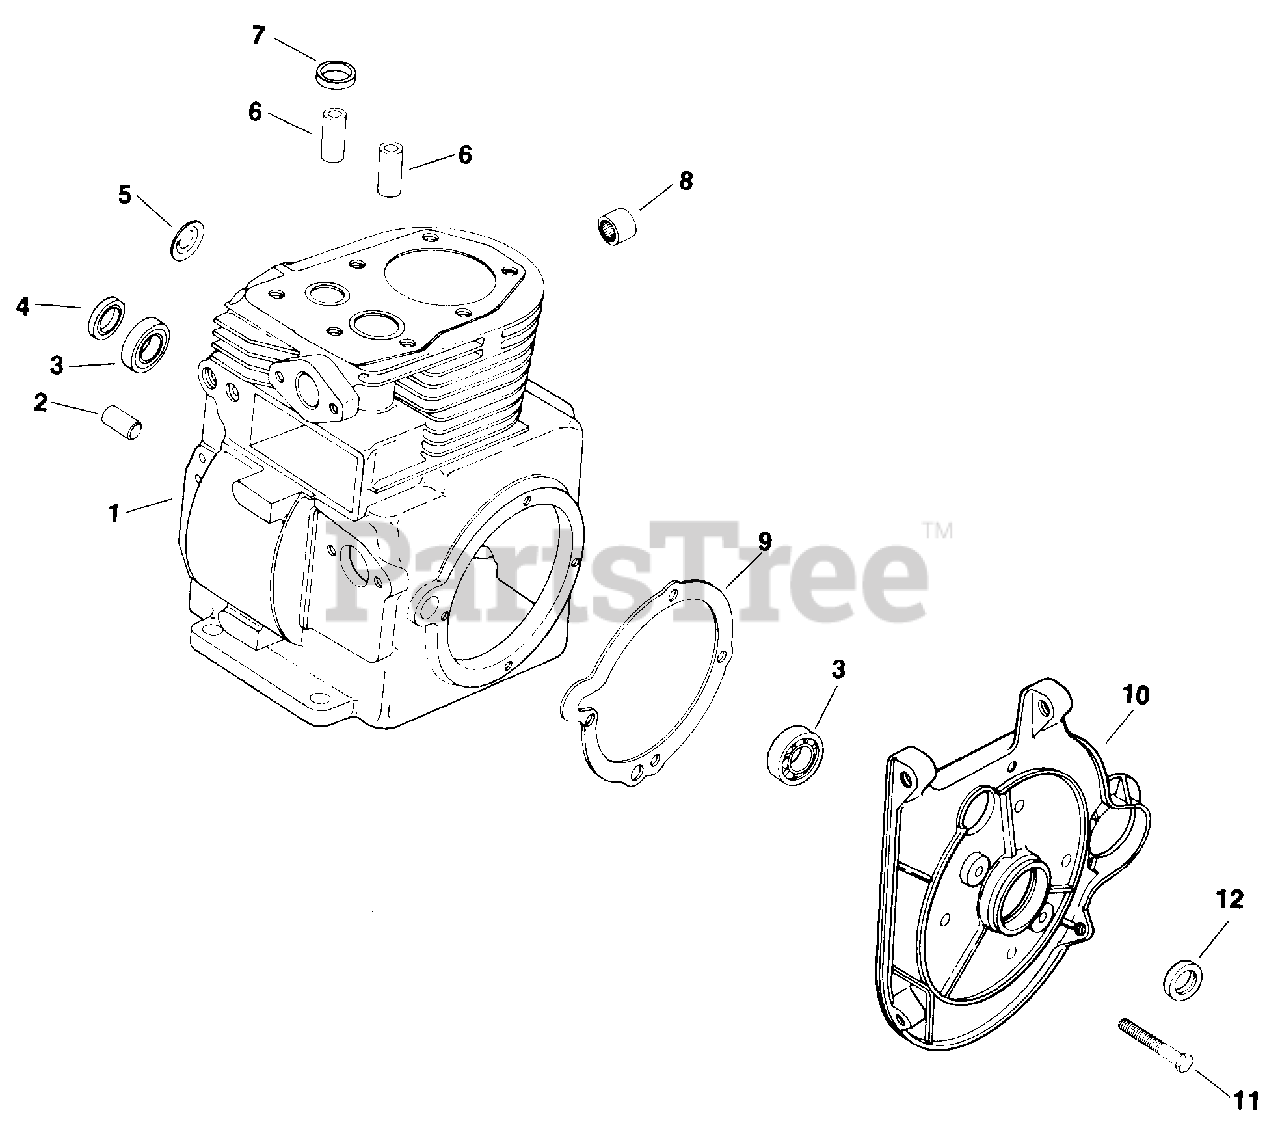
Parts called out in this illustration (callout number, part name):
2	Governor Shaft
3	Ball Bearing
4	Seal, Rear Oil
5	Plug, Expansion
6	Guide, Valve
7	Insert, Exhaust Valve
8	Bearing, Ball
9	Gasket, Bearing Plate
10	Plate, Bearing
11	Screw, H.C. 1/4-20 x 3/4
12	Seal, Front Oil
